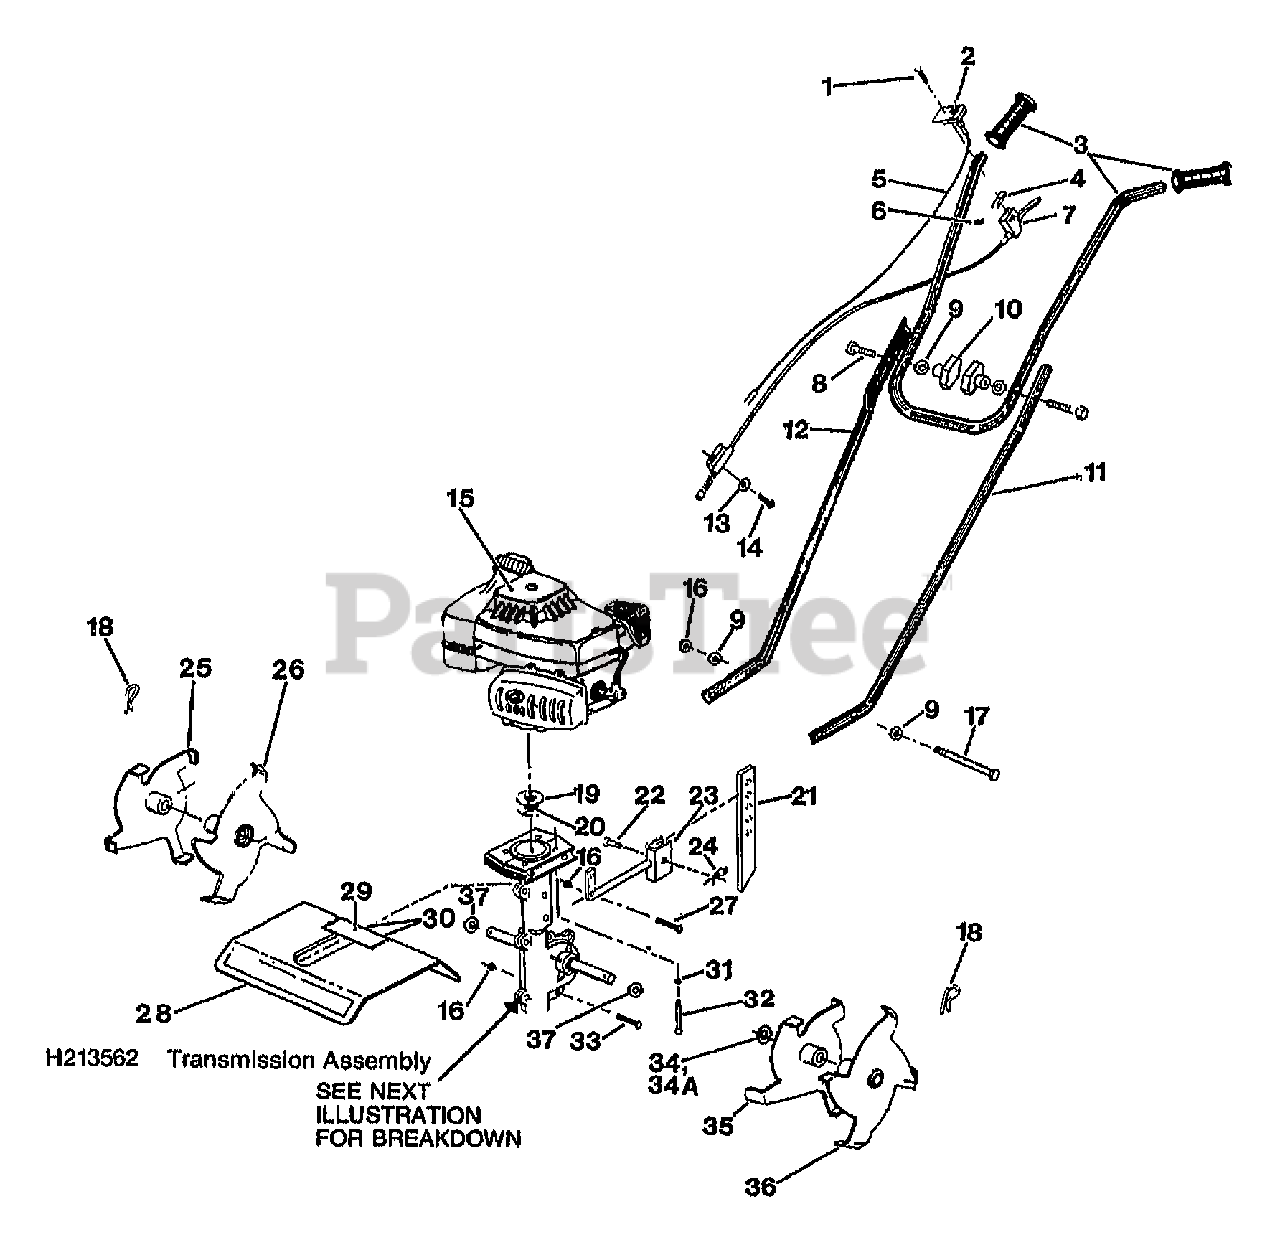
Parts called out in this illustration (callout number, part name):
1	SCR-PH HD M10-24X1.375
2	ASSM-SWITCH W/BRKT HHT
3	ASSM-UPR HANDLEBAR
4	PAD-ISOLATOR TRIGGER
5	HARNESS-WIRE
6	NUT-WELD #10-24
7	ASSM-TRIGGER & CABLE
8	SCR-CURVED HD 5/16-18X2.0
9	WASHER-BOW 1.0X.328X.059
11	H/BAR-LWR LH HHT
12	H/BAR-LWR RH HHT
13	WASHER-FLAT SH
14	SCR-HH M8-32X1.0
15	ENGINE, TECUMSEH TC-200-2026C
16	NUT-LK 1/4-20
17	SCR 1/4-20X4 1/2 BOLT 90036
18	PIN-HITCH .149DIA
19	CLUTCH-ROTOR SPEEDYHOE
20	SPRING-CLUTCH
21	DRAGSTAKE-PNT
22	PIN-CLEVIS
23	ASSM-BRKT DRAGSTAKE HHT
24	CLIP-HAIRPIN .07 DIA
25	ASSM-TINE OUTER RH
26	ASSM-TINE INNER RH
27	BOLT 1/4-20X1.25 (ATTACHES DRAG STAKE TO TRANSMISSION)
28	TINE COVER W/DECAL
29	PLATE-REAR TINE COVER
30	SCR-PHP M10-32X.38 STH ZP
31	WASHER-.88X312X.08 ZP
32	SCR-HH 1/4-20X2.00 GR5
33	SCR-HH 1/4-20X.75 G5 ZP
34	KIT-DUST CAP
34A	SCR M10-32X.25
35	ASSM-TINE INNER LH
36	ASSM-TINE OUTER LH
37	WASHER-FELT 1.5X.72X.13
